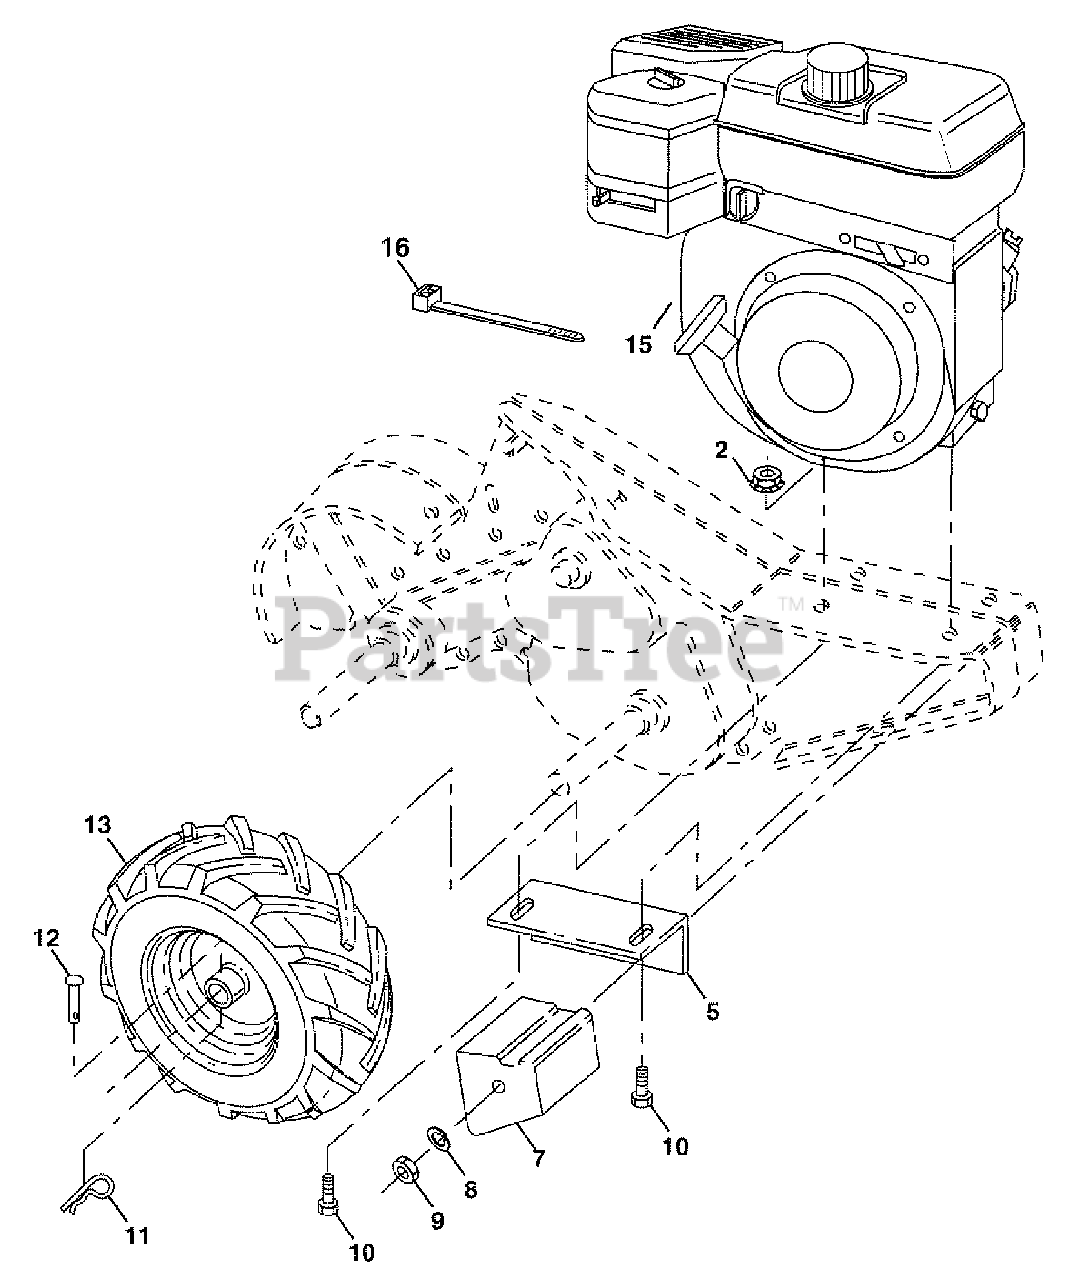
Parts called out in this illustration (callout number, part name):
2	Nut, Hex Flange
5	Bracket, Reinforcement
7	Counterweight, R.H.
8	Washer, Lock 3/8
9	Nut, Hex 3/8-16
10	Bolt, Hex 5/16-18x1-1/2
11	Ciip, Hairpin
12	Rivet, Drilled
13	Tire
13	Rim
13	Tire Valve
16	Tie Cable
